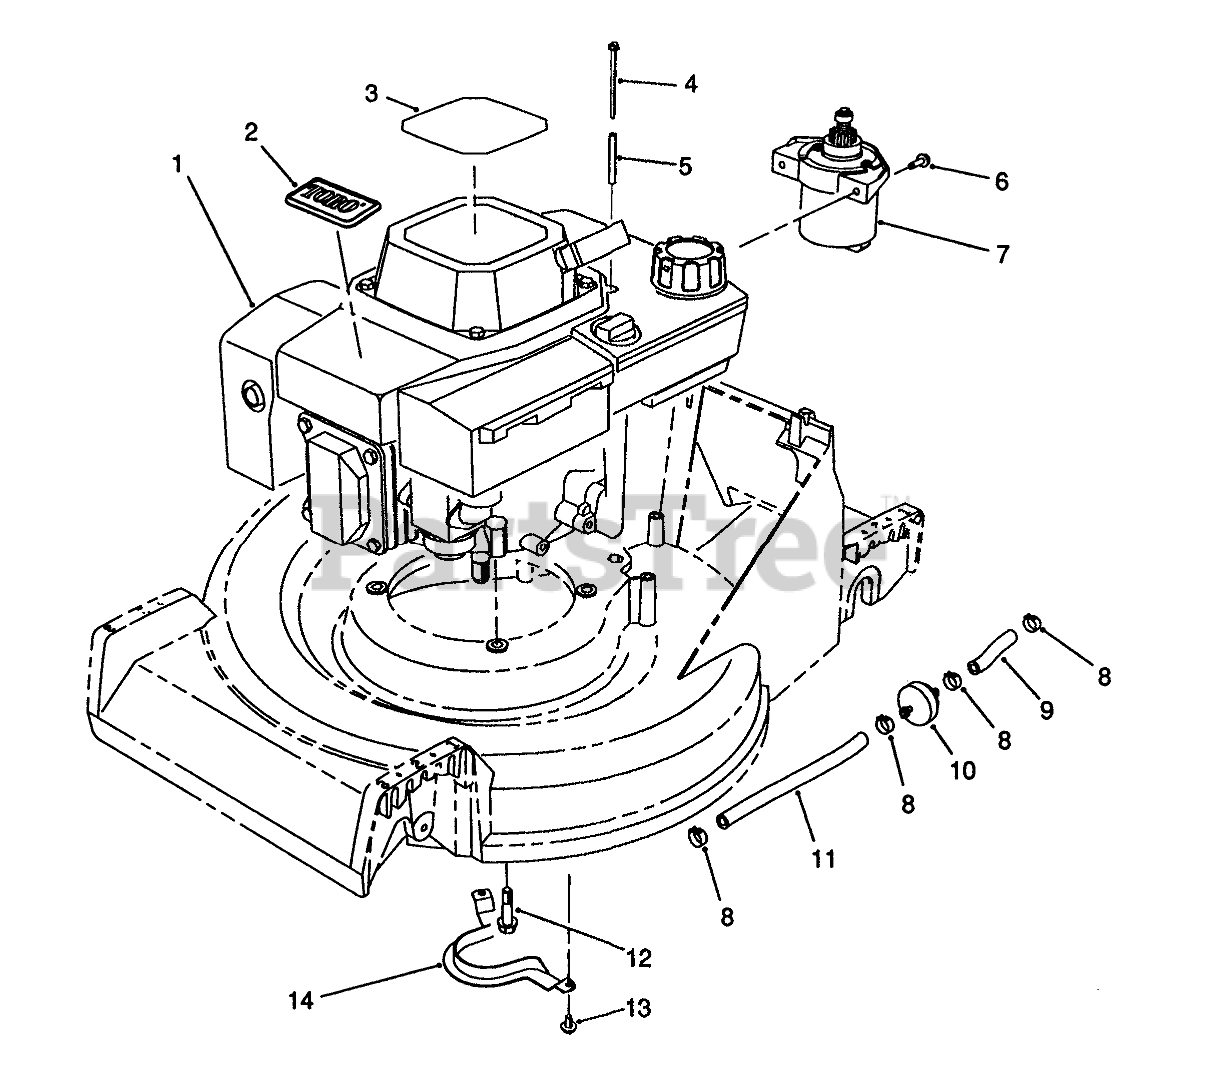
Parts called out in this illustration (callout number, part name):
1	ENGINE ASSY OHV BBC/K
2	TORO LOGO PLT
3	DECAL - OHV RECOIL
4	THRD FORMING SCREW
5	TUBULAR SPACER
6	SCREW
7	STARTER MOTOR ASM
8	CLAMP-FUEL LINE
9	LINE-GAS
10	FILTER-FUEL
11	HOSE-FUEL
12	SCREW-HWHTF
13	SCREW-HWHTF
14	Guide-Belt
